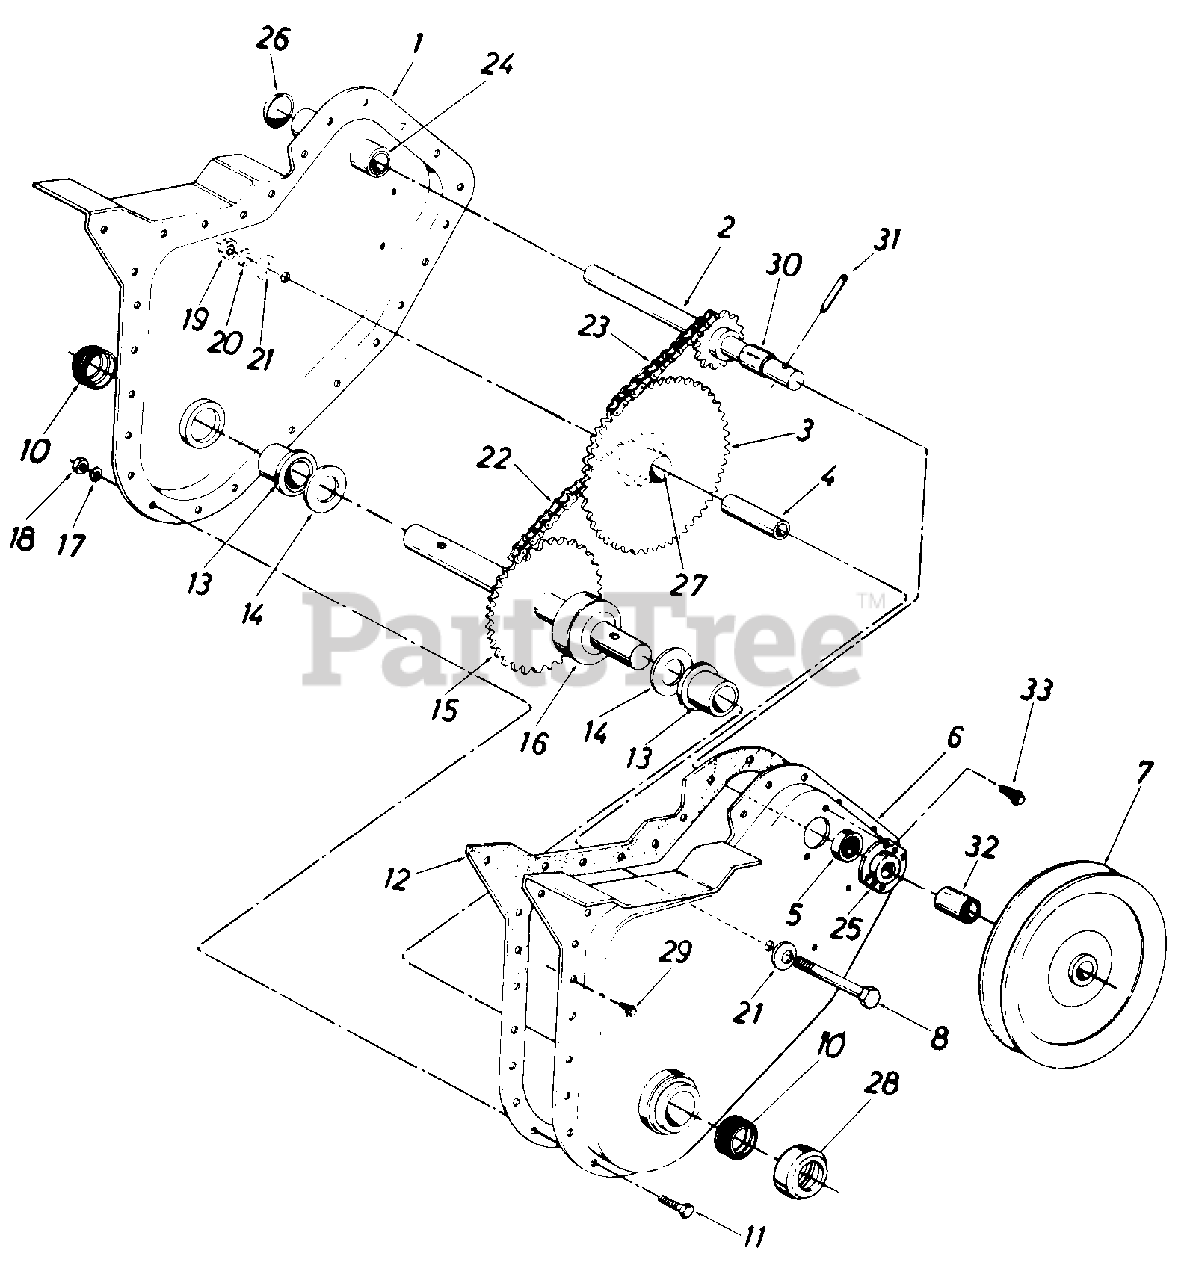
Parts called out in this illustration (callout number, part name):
1	Chain Case Ass'y.-R.H.
2	Input Shaft Ass'y.
3	Hub and Sprocket Ass'y.
4	Bearing Inner Race
5	Ball Bearing
6	Chain Case Ass'y.-L.H.
7	Pulley-Chain Case 5-1/2 x 1/2
8	Hex Bolt 3/8-24 x 2.50" Lg.
11	Hex Bolt 1/4-28 x .625" Lg.
12	Gasket
13	Flange Brg. .879 I.D.
14	Fl-Wash. .88 I.D. x 1.50 O.D. x .030
15	Tine Shaft Ass'y.
16	Spacer 718" I.D. x 2.0" O.D. x.68" Lg.
17	L-Wash. 1/4" Scr.
18	Hex Nut 1/4-28 Thd.*
19	Hex Ins. L-Nut 3/8-24 Thd.
20	L-Wash. 3/8" I.D.*
21	Bell-Wash. .406 I.D. x 1.130 O.D.
22	Chain #420-.50" Pitch x 38 Links
23	Chain #35-.375" Pitch x 50 Links
24	Bearing .62" I.D. x .813 0 O.D. x 1.31
25	Bearing Housing
26	Expansion Plug 13/16" Dia.
27	Bearing
29	Hex Wash. Hd. Self-Tap Scr. 1/4-20 x .50" Lg.
30	Spacer .630 I.D. x .77 O.D. x .38" Lg.
31	Spring Pin Spiral 1/4" Dia. x 1 1/2 " Lg.
32	Spacer .647 x 1.25"
33	Hex Wash. Hd. Self-Tap Scr. 1/4-20 x .38" Lg.
